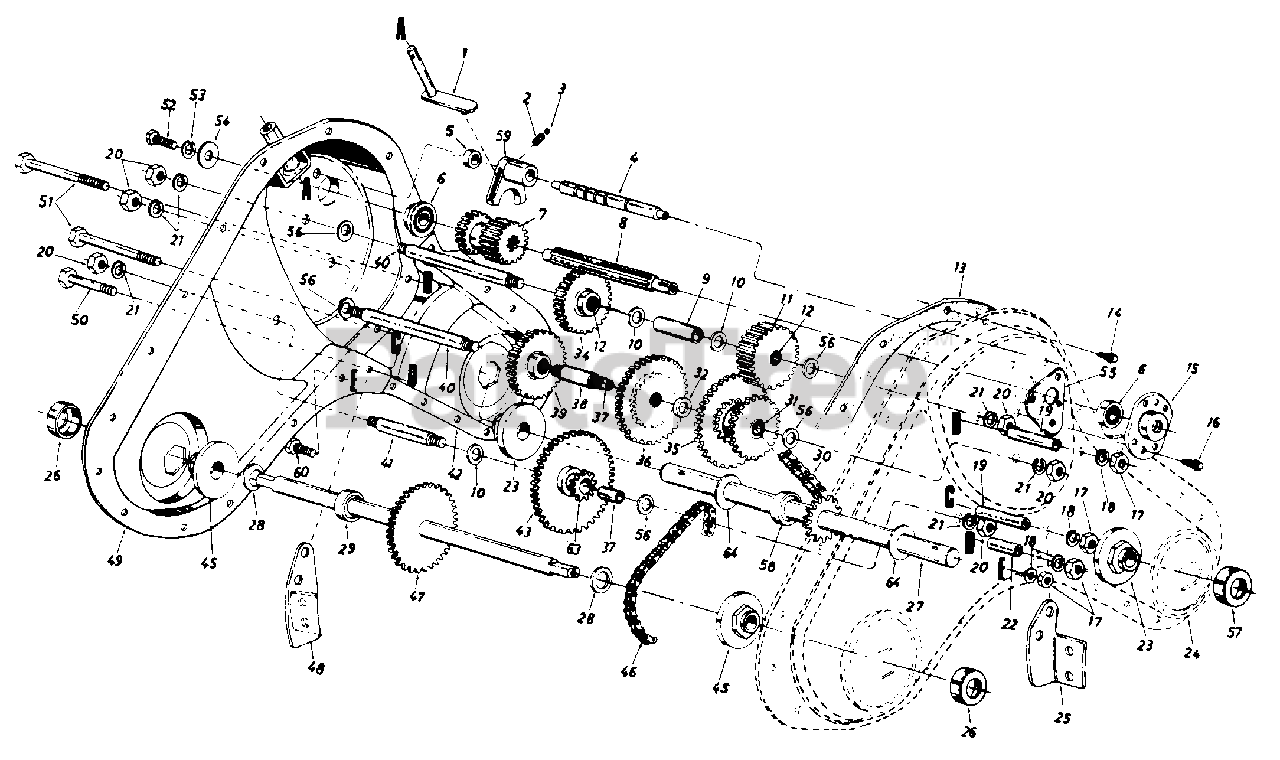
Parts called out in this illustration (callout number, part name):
1	Shifting Bracket Ass'y.
2	Compression Spring .50" Lg.
3	Ball Detent .250" Dia.
4	Detent Shaft 1/2" Dia.
5	Spacer .505" I.D. x .88" O.D.
6	Ball Brg. .62" I.D. x 1.38"
7	Spur Gear 16T
8	Input Spline Shaft 7/8"
9	Spacer .657" I.D. x 2.85" Lg.
10	Fl-Wash. .640" I.D. x 1.24"
11	Spur Gear 30T 7/8" I.D.
12	Needle Bearing 5/8" I.D.
13	Gasket Trans. Hsg.
14	Hex Wash. S-Tap Scr. 1/4-20 x.50" Lg.
15	1-3/8" Dia. Bearing Housing
16	Hex TT-Tap Scr. 1/4-20 x .75"
17	Hex Nut 5/16-18 Thd.
18	L-Wash. 5/16" I.D.
19	Spacer 1.56" Lg.
20	Hex Nut 7/16-20 Thd.
21	Bell-Wash. .45" I.D. x 1.0
22	Spacer 1.015" Lg.
23	Tine Shaft Brg. 1.002 x 2.50
24	Trans. Housing Ass'y. L.H.
27	Tine Shaft Ass'y. 1" O.D.
28	Fl-Wash. .75" I.D. x 1.5" O.D.
29	Spacer .75" I.D. x .50" Lg.
30	Chain #50 5/8 Pitch x 52 Links Endless
31	Needle Bearing 5/8" I.D.
32	Fl-Wash. 5/8" I.D.
34	Spur Gear 30T 12/16" I.D.
35	30/44T Gear Ass'y. Comp.
36	Spur Gear 44T
37	Sleeve Bearing
38	Gear Hub 3/4" I.D. x 3" Lg.
39	Spur Gear 30T 1.0" I.D. x 1/2" W
40	Jack Shaft 5/8" Dia. x 5
41	Jack ShaR 5/8" Dia. x 2.38
45	Wheel Brg. .752" x 2.5"
46	#420 Chain 1/2 Pitch x 50 Links Endless
47	Wheel Shaft Ass'y. 15.6"
51	Hex Bolt 5/16-18 x 2.5
52	Hex Bolt 1/4-20 x .62" Lg.
53	L-Wash. 3/8" I.D.
54	Fl-Wash. 1/4" I.D. x .93" O.D.
55	Gear Positioner Bracket
56	Fl-Wash. 7/16" I.D. x 1-3/8"
57	Dust Cover Ass'y. 1" Shaft
58	Spacer 1 I.D. x 2" O.D.
59	Shifting Fork
60	Hex Bolt 5/16-18 x .75" Lg.
63	1 OT Sprocket Ass'y.
64	Thrust Wash. 1.03" I.D. x 1.62" O.D.
